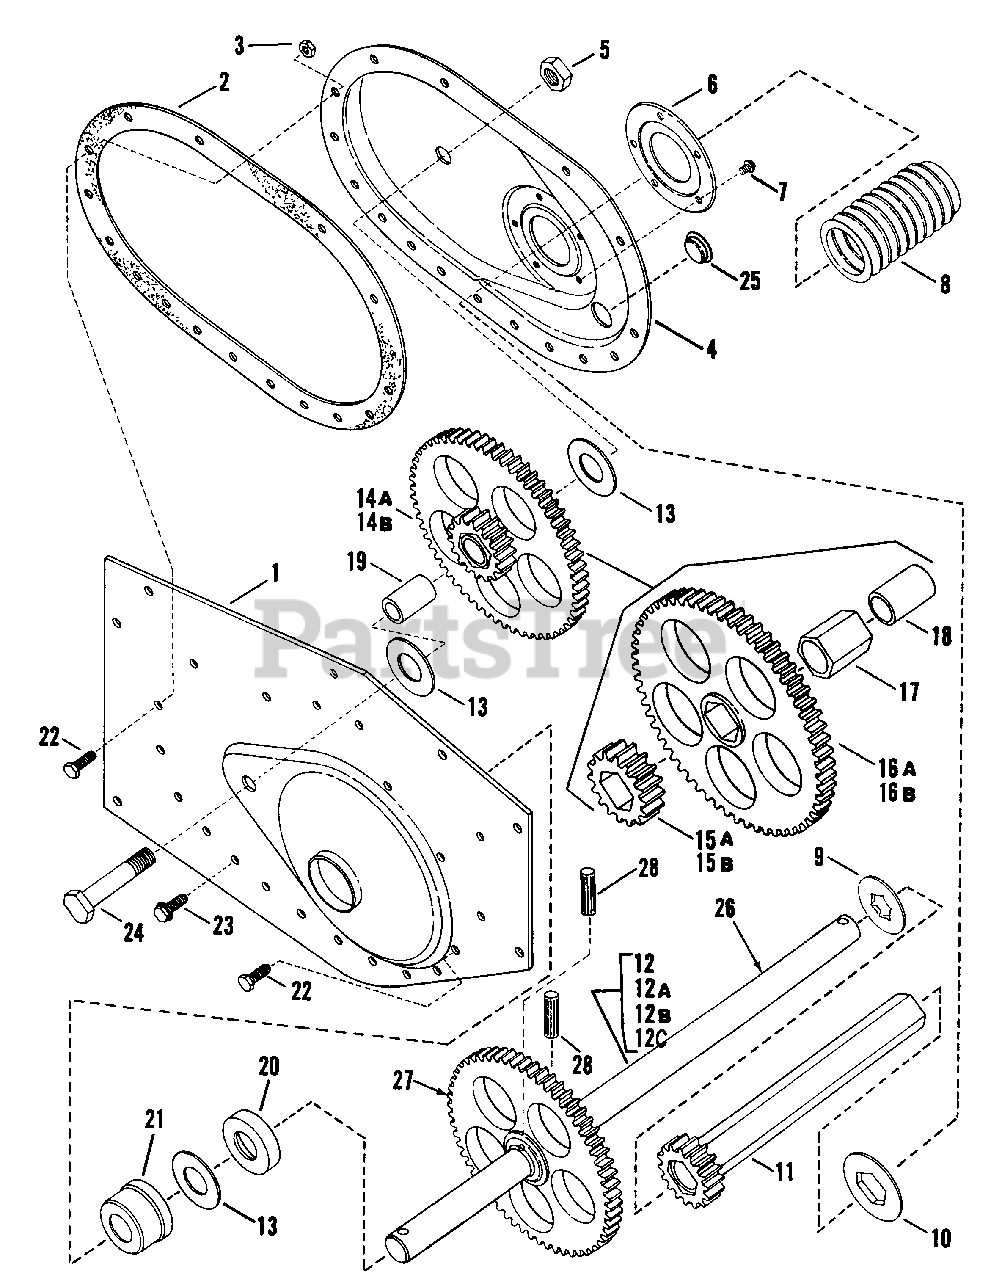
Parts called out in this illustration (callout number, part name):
1	FRAME, Left Side
3	NUT, 1/4-28 Hex Top Lock
5	NUT, 1/2-20 Hex Jam Center Lock
6	RETAINER, Boot
7	SCREW, #10-32 x 1/4" Hex Washer (slotted) Self-Tap
8	SEAL, Short
9	WASHER, Thrust
10	WASHER, Plastic
11	ASSEMBLY, Tube Drive
12	WELDMENT, Axle
12A	AXLE REPLACEMENT
12B	AXLE REPLACEMENT
12C	ASSEMBLY, Axle & Gear
13	WASHER, Thrust
14A	GEAR ASS'Y, Cluster
14B	GEAR ASS'Y, Cluster
15A	GEAR, 16 Tooth/10 P Hex
15B	GEAR, 15 Tooth/10 P Hex
16A	GEAR, 63 Tooth
16B	GEAR, 64 Tooth
17	TUBE, Hex
18	BEARING
19	SHAFT
21	BEARING, Axle .75" ID x 1.626"/1.75" OD x 1.06" Long
22	SCREW, 1/4-28 x 1/2" Hex Head Cap, Grade 5
23	SCREW, 1/4-20 x 1/2" Hex Washer Self-Tap
24	SCREW, 1/2-20 x 1-7/8" Hex Head Cap, Grade 5
25	PLUG, 3/4"
26	SHAFT, Axle
27	GEAR- 64 Tooth
28	PIN, Groove
